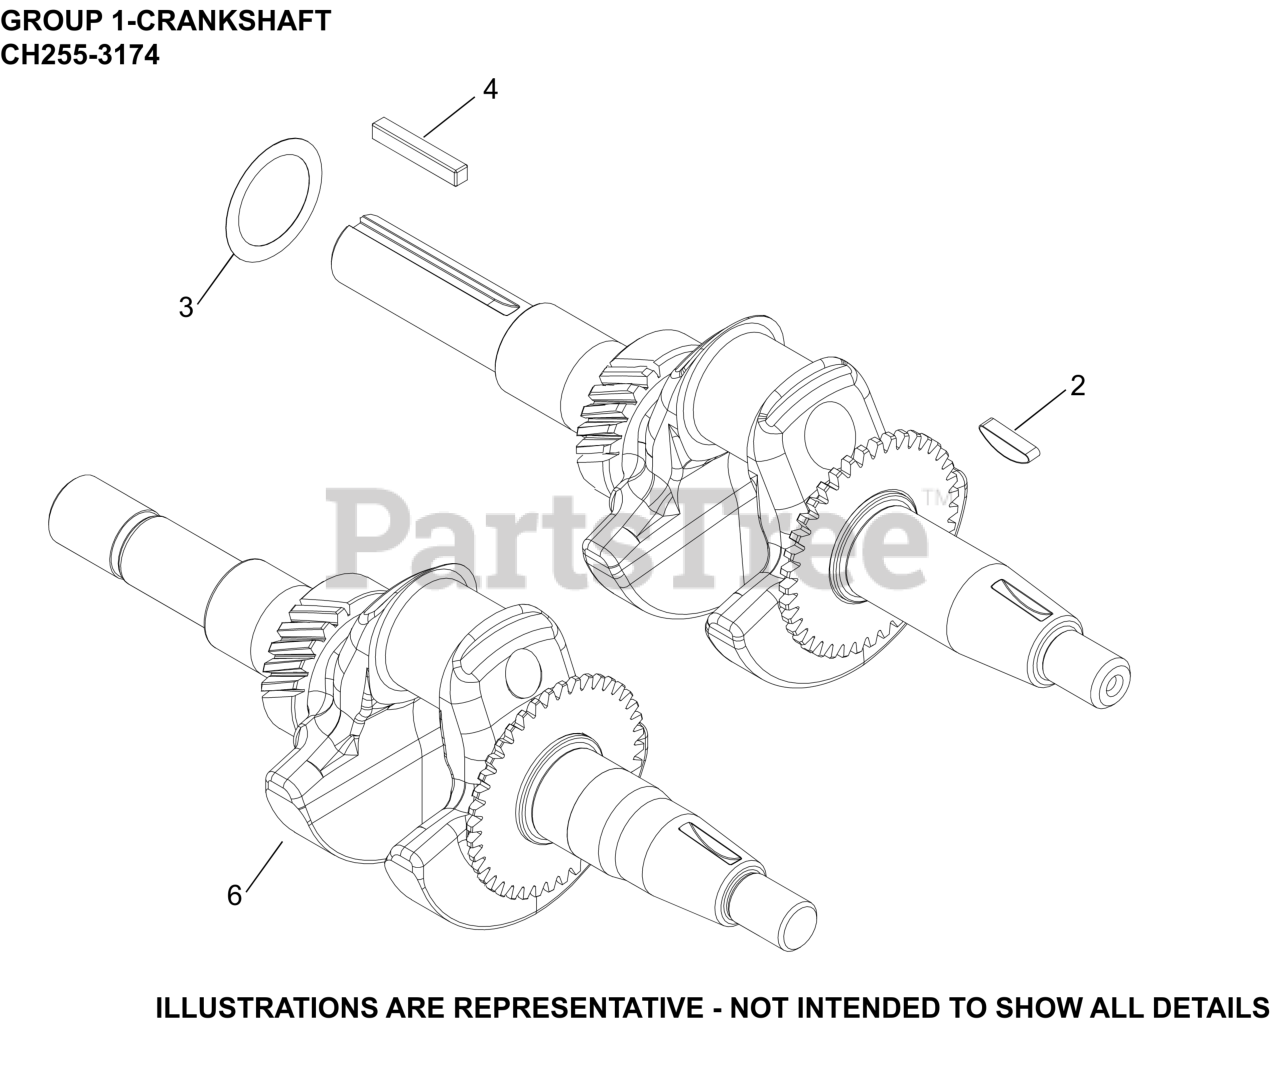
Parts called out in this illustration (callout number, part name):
2	KEY, FLYWHEEL
3	KIT, THRUST SHIM
4	KEY, SQUARE
6	CRANKSHAFT, ASSEMBLY
